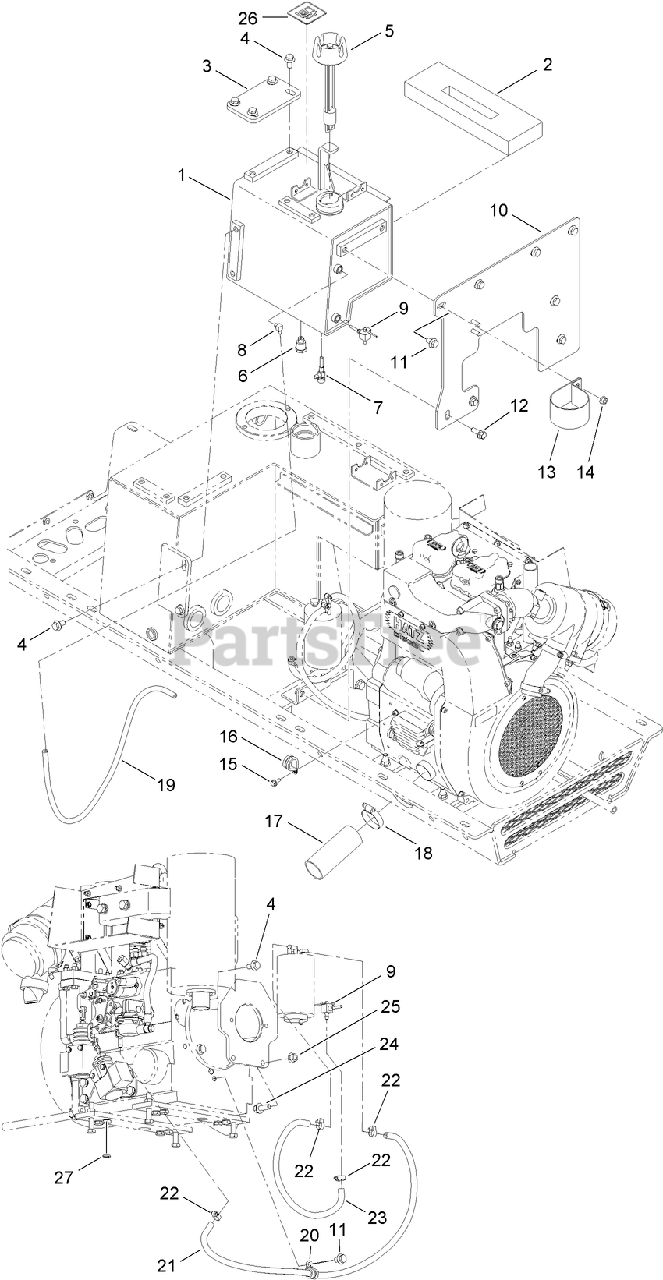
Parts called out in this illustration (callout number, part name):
1	CELL-FUEL TANK
2	ISOLATOR-LIFTEYE
3	PLATE-MOUNTING, HYD FUEL
4	SCREW-HHF
5	GAUGE-FUEL
6	PLUG-HH, MAGNETIC
7	VALVE AND STRAINER ASM
8	FITTING-HYD, ELBOW
9	VALVE-STRAINER
10	SHIELD-HEAT
11	SCREW-HHF
12	SCREW-HHF
13	STRAP-SEPARATOR, WATER
14	NUT-HF
15	SCREW-HHF
16	CLAMP
17	HOSE-BREATHER
18	CLAMP-HOSE
19	HOSE-FUEL, RETURN
20	CLAMP
21	HOSE-FUEL
22	CLAMP-WORM
23	HOSE-FUEL
24	SCREW-HHF
25	NUT-HF
26	DECAL-DIESEL
27	WASHER-FLAT
